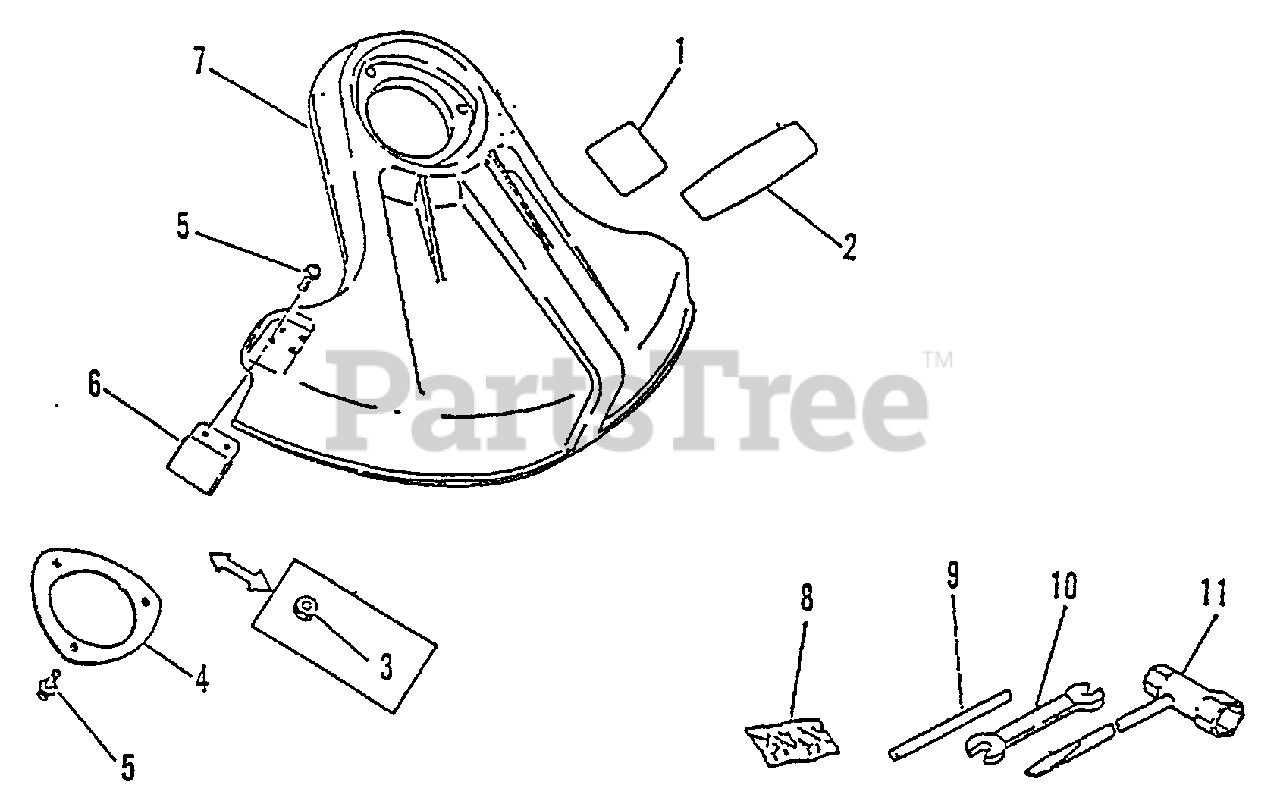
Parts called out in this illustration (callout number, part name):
1	LABEL - CAUTION
2	LABEL - ECHO
4	PLATE, SHIELD
5	SCREW - 5X16
6	KNIFE, TRIMMER LINE
7	DEBRIS SHIELD KIT
8	PIN, SPLIT - 2X22
9	LOCKING TOOL
10	SPANNER - 8X10mm
11	T-WRENCH - 17X19mm
